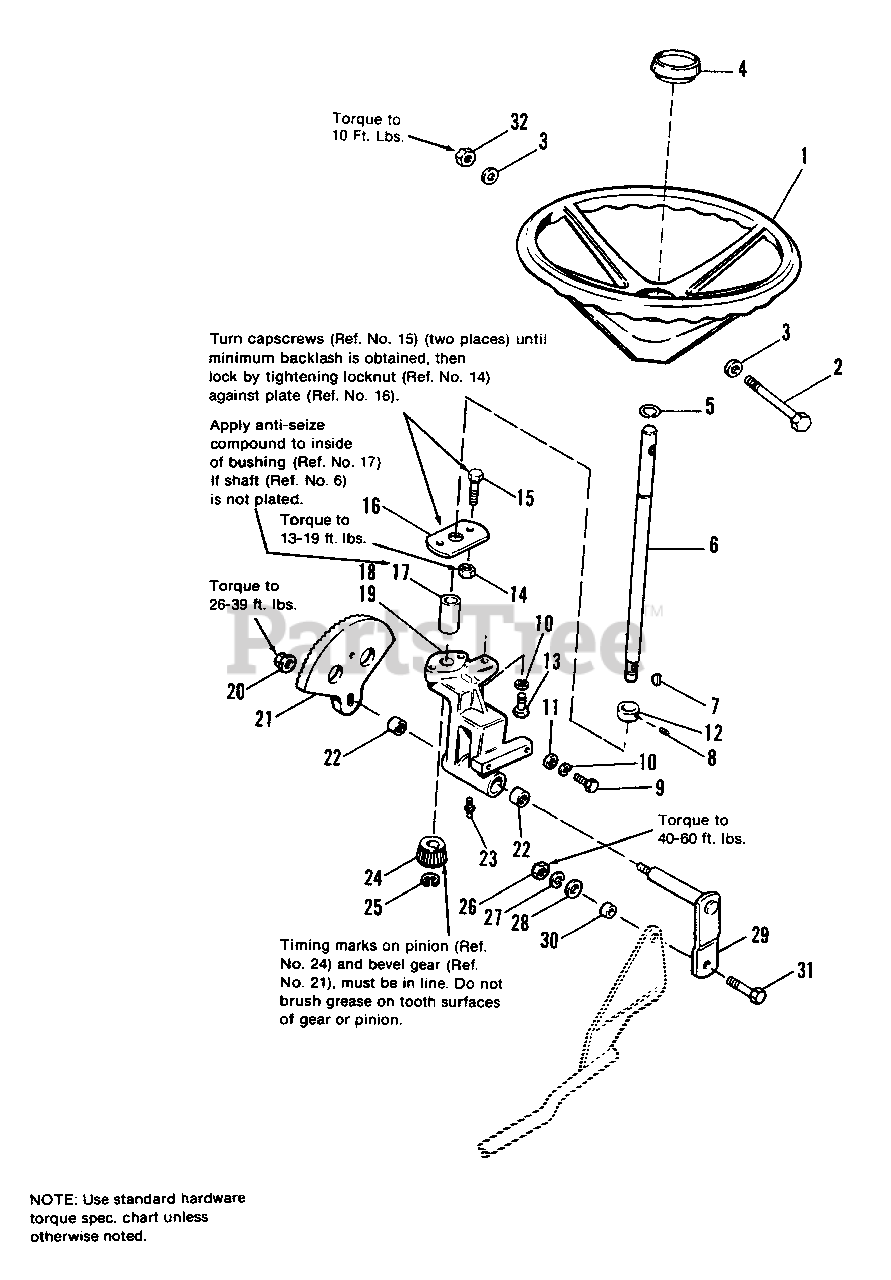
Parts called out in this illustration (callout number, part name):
1	WHEEL, Steering
2	BOLT, Hex, 5/16 x 3-1/2
3	WASHER, 5/16
4	CAP, Steering Wheel
5	RING, Retaining
6	SHAFT, Steering
7	KEY, Woodruff, #6
8	SETSCREW, 5/16-18 x 1/4
9	CAPSCREW, Hex Hd., 3/8-16 x 7/8
10	LOCKWASHER, 3/8
11	WASHER, Plain, 3/8
12	COLLAR, Set
13	CAPSCREW, Hex hd., 3/8-16 x 3/4
14	LOCKNUT, Hex, Jam, 3/8-16
15	CAPSCREW, Hex Hd., 3/8-16 x 1-1/4
16	PLATE, Steering
18	HOUSING ASSY., Steering (Incl. Ref. Nos. 17 & 22)
19	HOUSING ASSY., Steering
20	LOCKNUT, Hex, Flange, 7/16-14
21	GEAR, Bevel
22	BEARING, Needle
23	FITTING, Grease
24	PINION, Bevel
25	E-RING
26	NUT, Hex, Full, 1/2-13
27	LOCKWASHER, 1/2
28	WASHER, Plain, 1/2
29	ARM ASSY., Steering
31	CAPSCREW, Hex Hd., 1/2-13 x 1-1/2
32	LOCKNUT, Hex, Cntr. 5/16-18
